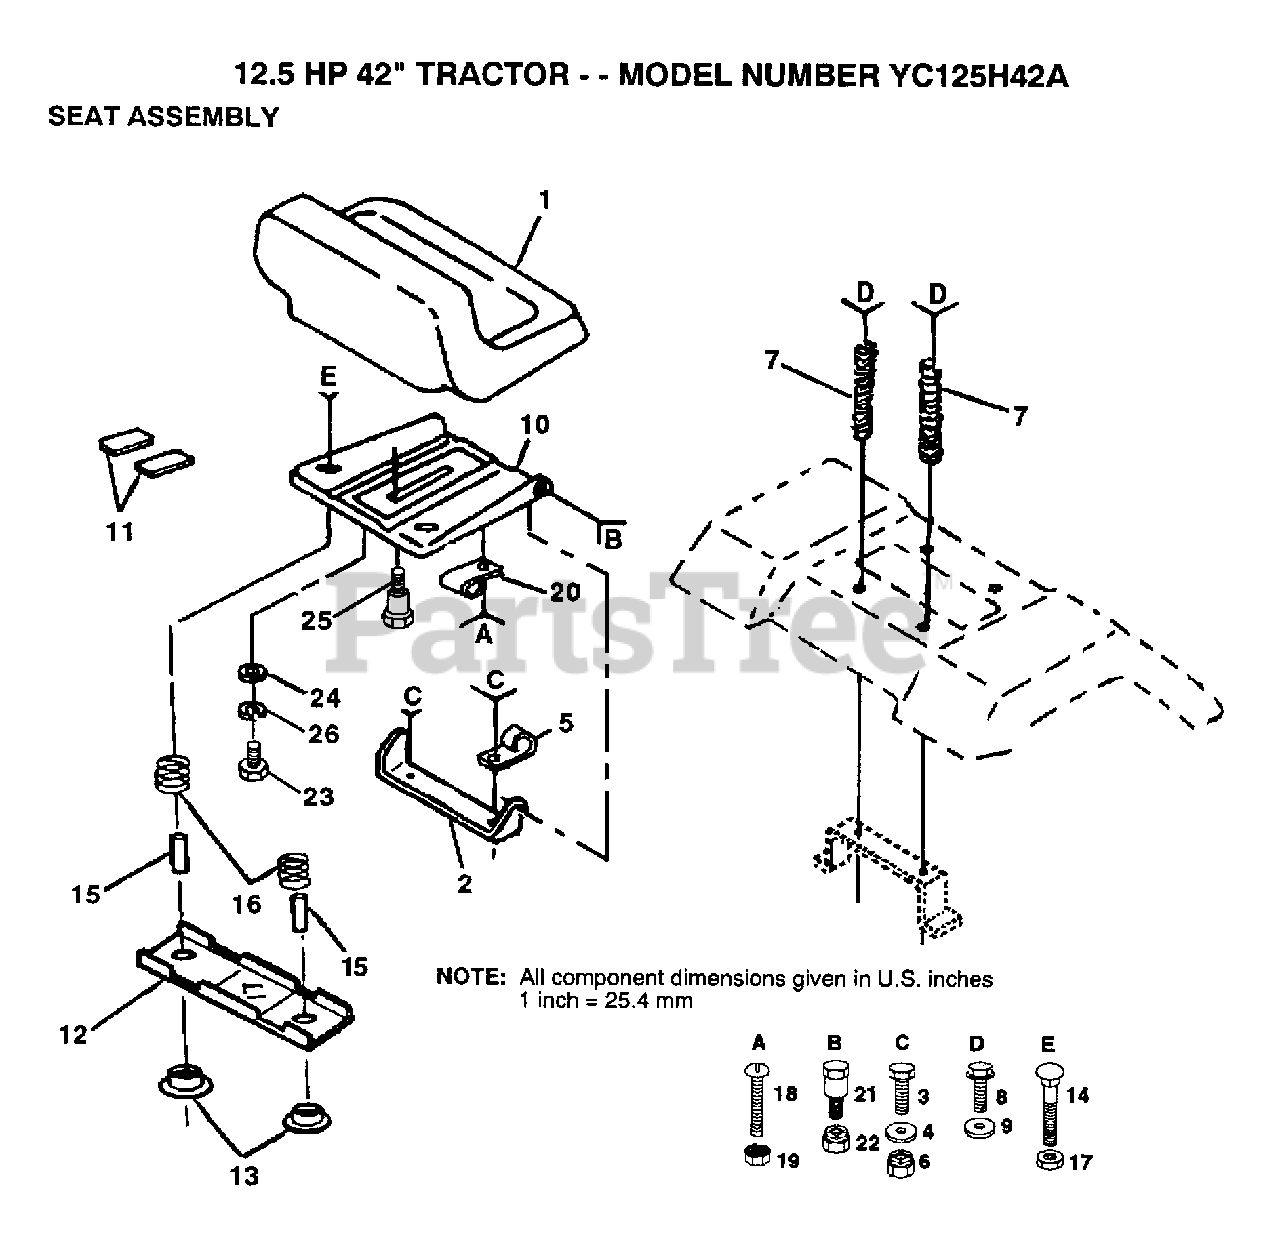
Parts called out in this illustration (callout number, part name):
4	WASHER PM
5	CLIP T
7	SPRING COMPRESSIO
8	SCREW GTV
9	WASHER
11	STRIP FORM
12	BRKT SWITCH
13	BUSHING
15	SPLIT SPACER
16	SPRING
19	"NUT,KEPS"
23	BOLT
24	WASHER
25	"BOLT,SHOULDER"
26	LOCKWASHER
